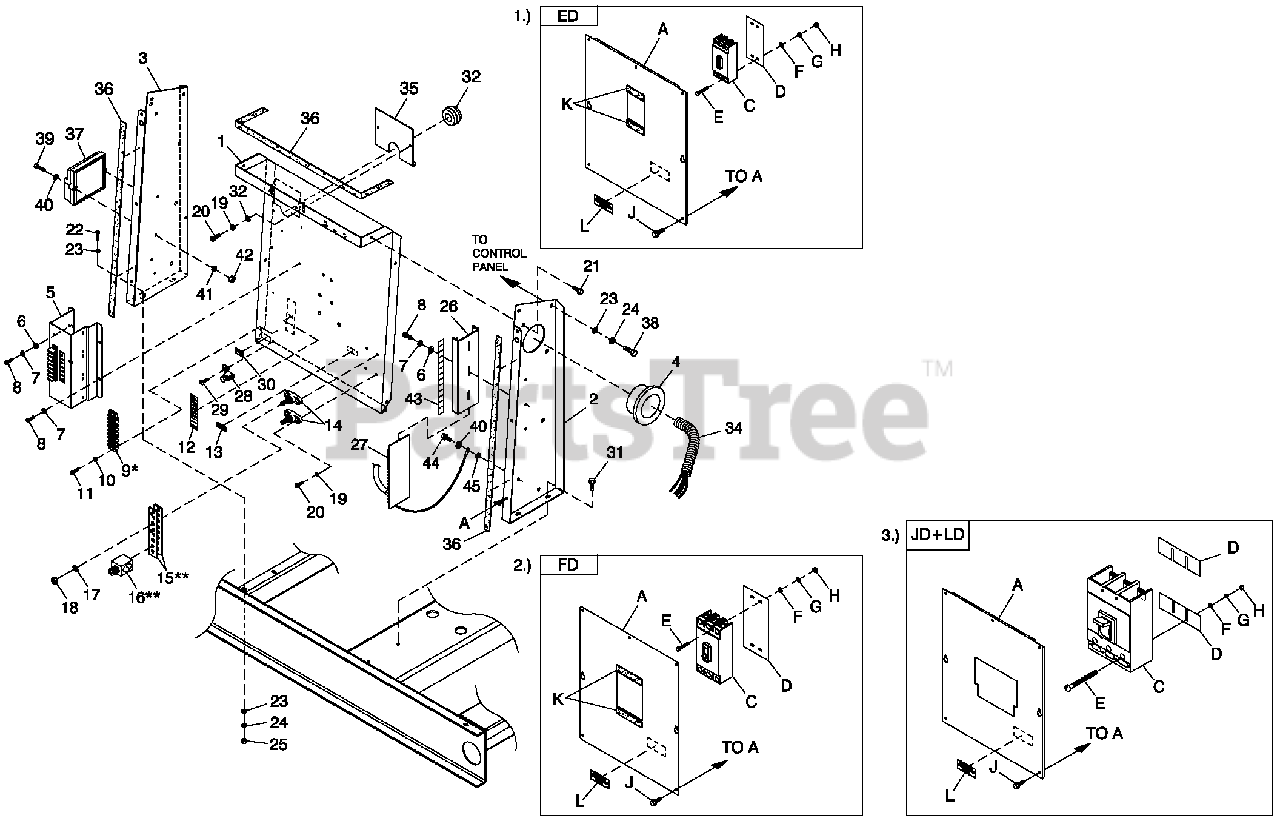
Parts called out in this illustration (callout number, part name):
1	PAN CB CONN BOX
1	UL CIRCUIT BREAKER (ED)
2	STAND RH CONTROL
2	UL CIRCUIT BREAKER (FD)
3	STAND LH CONTROL
3	UL CIRCUIT BREAKER (JD+LD)
4	BUSHING SNAP SB-2.5-31
5	ASSY PCB INTERFACE 1PH 240V
6	WASHER FLAT M4
7	WASHER LOCK #8-M4
8	SCREW PHTTM4-0.7X 10 ZYC
9	BLOCK TERM 20A 8 X 6 X 1100V
10	WASHER LOCK #6
11	SCREW PHTT # 6-32X1 /2 ZYC
12	DECAL CPL CUST CONN H CTRL
13	DECAL NEUTRAL
14	JUNCTION BLOCK 3/8-16
15	BUS BAR NEUTRAL BLOCK 390
16	LUG SLDLSS 600/250-1/0 X 1/4-28
17	WASHER LOCK 3/8
18	NUT HEX 3/8-16 STEEL
19	WASHER LOCK M5
20	SCREW PHTT M5-0.8X 16 ZYC
21	SCREW THF M6-1 X 16 N WA Z/JS
22	SCREW HHC M6-1.0X20G8.8
23	WASHER FLAT 1/4-M6 ZINC
24	WASHER LOCK M6-1/4
25	NUT HEX M 6X 1 .0G 8Y E LC H R
26	RAIL SNAPTRACK PCB HOLDER BULK
27	ASSY RELAY PCB 12VDC
28	LUG SLDLSS #6-14 X 13/64 CU
29	SCREW HHTT #10-32X3/8 CZ
30	DECAL GROUND LUG
31	SCREW HHTT M6-1.0X 16ZYC
32	WASHER FLAT M5
33	GROMMET 1.25 X .25 X .75
34	CONDUIT FLEX 2.0" ID
35	PLATE WIRE SNGLGALV
36	TAPE ELEC 1/2 FOAM (AS REQ'D)
37	ASSY PCB 5.4L IGN MOD PRGRMMED
38	SCREW HHC M6-1.0X 16 G8.8
39	SCREW PHM #8-32 X 2-3/4ZINC
40	WASHER FLAT #10 ZINC
41	WASHER LOCK #10
42	NUT HEX #10-32 STEEL
43	DECAL H-100 RB3 CUST CONN
44	SCREW HHTT M4-0.7X 8 ZP
45	WASHER SHAKEPROOF EXT #10 STL
46	SPACER .31 X .75 X 1 ST/ZNC
A	COVER ED CB STAND C3
C	CB0090A3P 480V SED4 LL
D	INSULATOR CBS(ED-3P)
E	SCREW RHM #10-32X4-1/2
F	WASHER FLAT #10 ZINC
G	WASHER LOCK #10
H	NUT HEX #10-32 STEEL
J	SCREW THF M6-1 X 16 N WA Z/JS
K	TAPE ELEC 1/2 FOAM (AS REQ'D)
L	DECAL CUSTOMER CONNECT INSIDE
A	COVER FD CB STAND C3
C	CB0175A3P 600V SFD6 LL
D	INSULATOR CB FD FRAME 30MIL
E	SCREW SHC 1/4-20 X 4 G8.8 NZ
F	WASHER FLAT 1/4-M6 ZINC
G	WASHER LOCK M6-1/4
H	NUT HEX 1/4-20 STEEL
A	COVER JD/LDCB STAND C3
C	CB0300A3P 600V SJD6 LL
D	INSULATOR CIRCUIT BR. JD/LD
E	SCREW RHM 1/4-20X3
